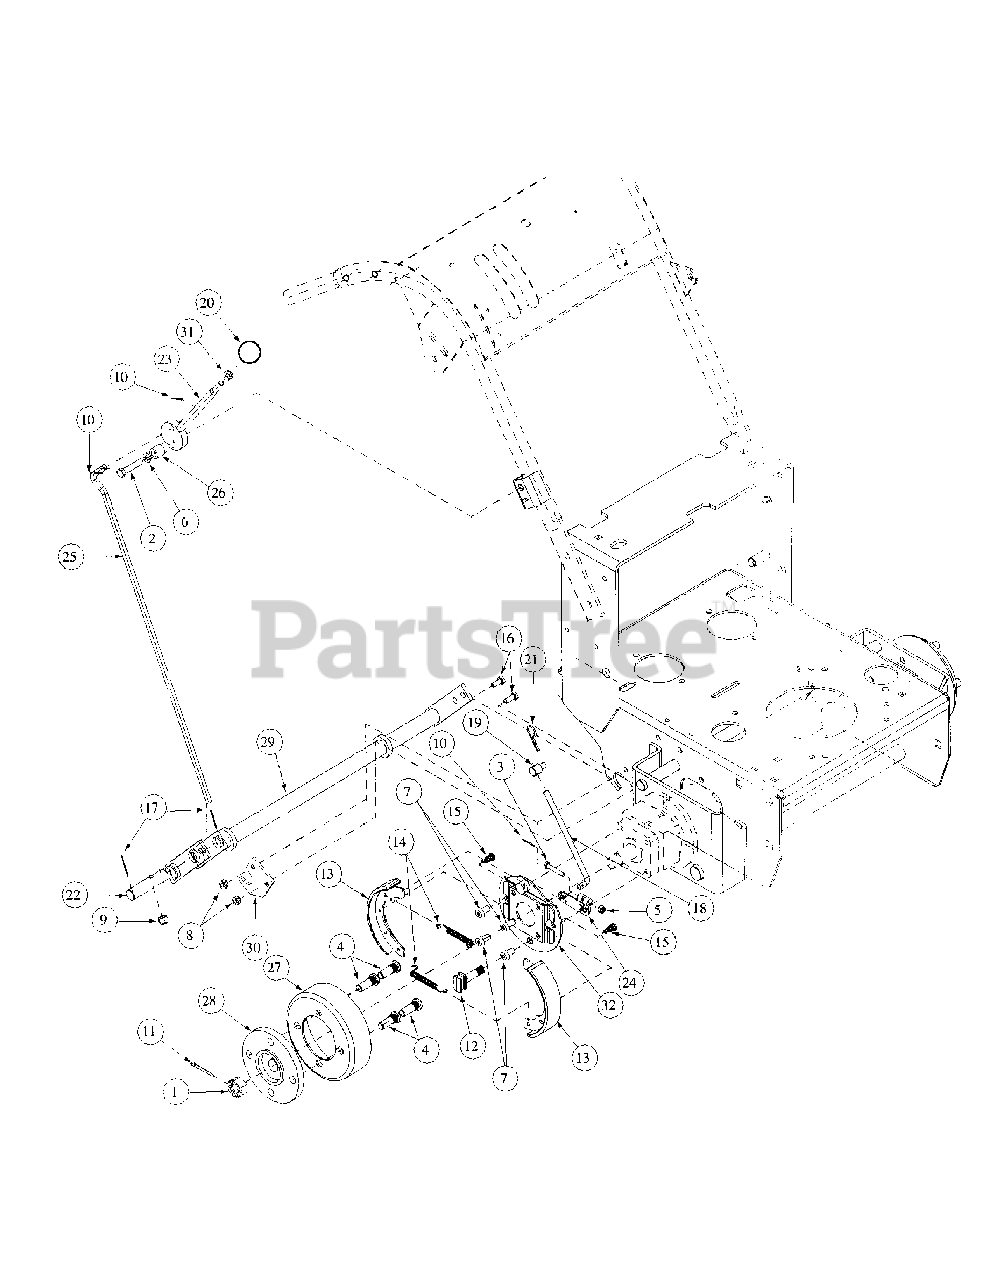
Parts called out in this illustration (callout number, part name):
1	Nut, Castle, 3/4-16
2	Capscrew, 3/8-16 x 1" Grade 5 Zinc
3	Cap Screw, 1/4-20 x 1.50, Grade 5
4	Bolt, Wheel, 1/2-20 x 1-3/8
5	Lock Nut, Nylon Insert, 1/4-20 Grade A
6	Lock Washer, 3/8 Zinc
7	Capscrew, Socket Button Hd., 3/8-16 x 3/4 Zinc
8	Nut, 5/16-18, Nylock
9	Nut, Nylon Insert, 3/8-16 Grade A
10	Cotter Pin, 3/32 x 3/4, Zinc
11	Cotter Pin, 5/32 x 1-1/2 Zinc
12	Brake Cam, Actuating
13	Brake Shoe w/Lining, 6 x 1-1/4
14	Brake Spring, Tension
15	Brake Spring, Anti-Vibration
16	Cap Screw, 5/16-18 x 3/4, Grade 5
17	Cotter Pin, 3/32 x 1, Zinc
18	Brake Rod
19	Swivel Joint
20	Knob, Red, Shift w/Insert
21	Hair Pin, 3/8"-1/2"
22	Joint, Brake Pull
23	Lever Assembly, Brake
24	Brake Clamp, Control Assembly, Hydro
25	Rod, Long Brake, Hydro WB
26	Pivot Spacer, Hydro WB
27	Brake Drum
28	Hub, Wheel Motor
29	Brake Shaft Assembly WT
30	Pivot Mount, Brake
31	Nut, 3/8-16, Jam, Grade 2
32	Brake Backing Plate
